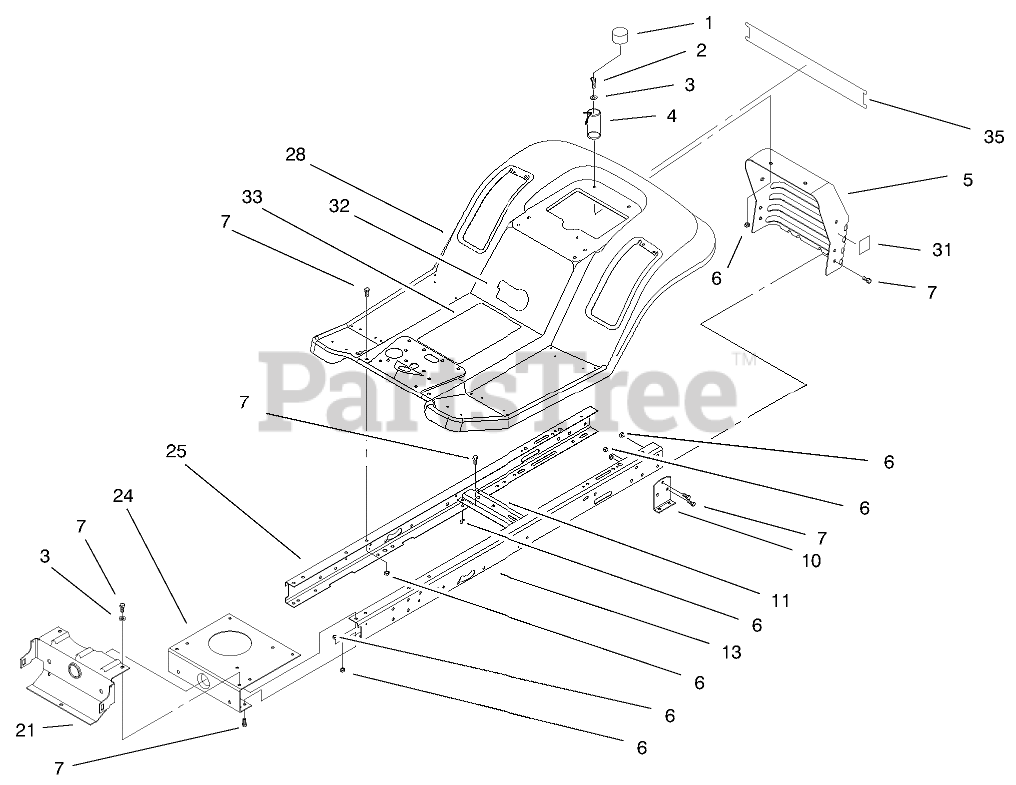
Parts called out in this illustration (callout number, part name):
1	CAP-PROTECTOR
2	SCREW-HH
3	WASHER-PLAIN
4	SPRING-COMPRESSION
5	SUPPORT-SEAT/REAR HITCH
6	NUT-LOCK, NI
7	SCREW-HH
10	BRACKET-TRANSAXLE, MOUNTING
11	BRACKET-IDLER PIVOT
13	RAIL-FRAME, LH
21	SUPPORT-FRONT, AXLE
24	PLATE-MOUNTING, ENGINE
25	RAIL-FRAME, RH
28	REAR BODY ASM
31	DECAL - DUMP VALVE
32	Decal-USA (only on: 71225)
33	Decal-Instruction Hydro (only on: 71225)
33	Decal-Instruction (only on: 71241)
35	DECAL-REAR, BODY
